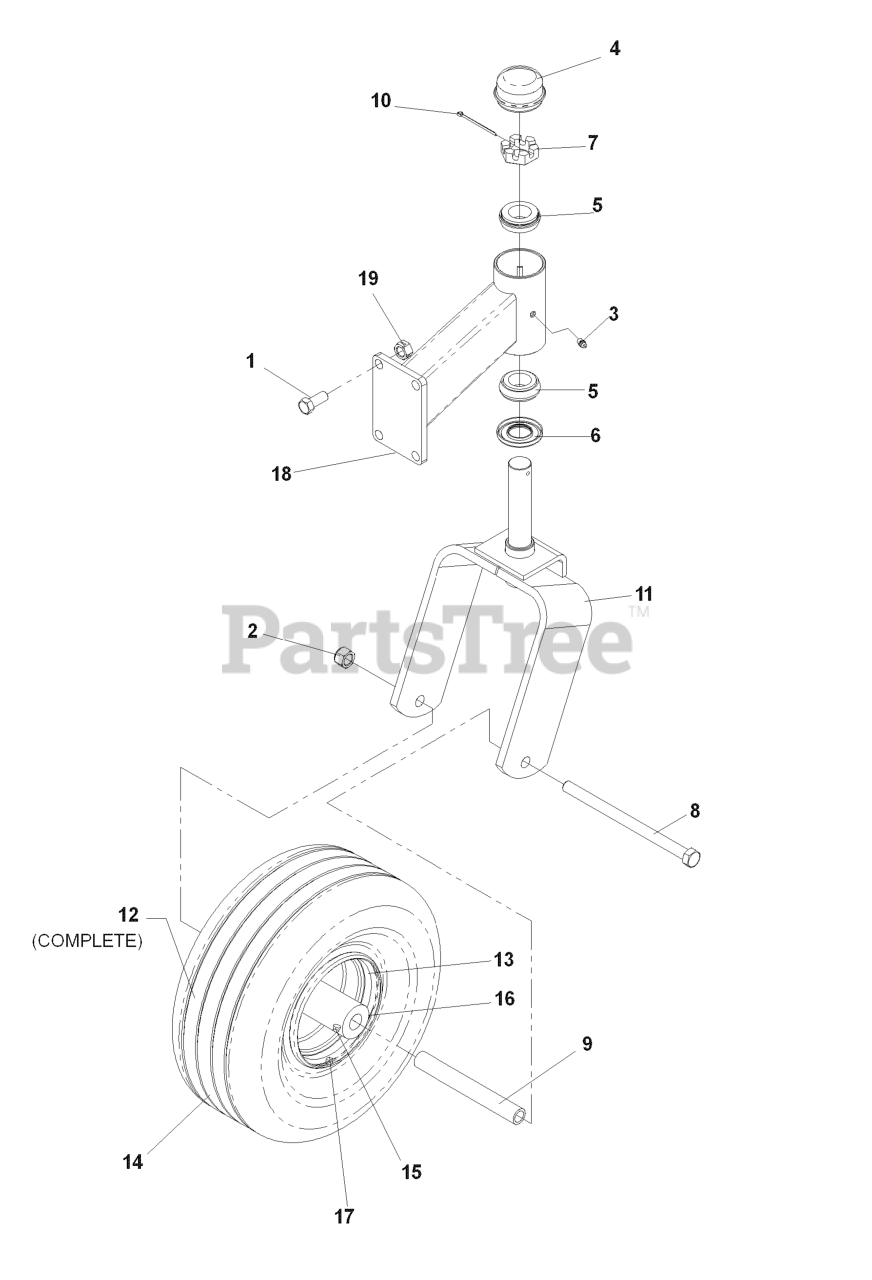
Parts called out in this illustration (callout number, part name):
1	HCS 7/16-14 X 1 GR 5 ZD
2	NUT 1/2-13 HEX NYLOC ZD
3	ZERK
4	GREASE CAP
5	TAPERED ROLLER BRG
7	NUT 1"C HEX SLOTTED
8	SCREW 1/2C X 7 1/2 HEX CAP
9	SPACER, CASTER
10	COTTER PIN 1/8 X 2
11	CASTER YOKE ORANGE
12	TIRE.ASSEM.13X5-6.SMOOTH.SILVE
13	RIM
14	TIRE - FRONT
15	ZERK 1/8 NPT
16	BEARING RETAINER
17	VALVE STEM TR-412
18	CASTER ARM, ORG
19	NUT 7/16C CENTERLOCK
